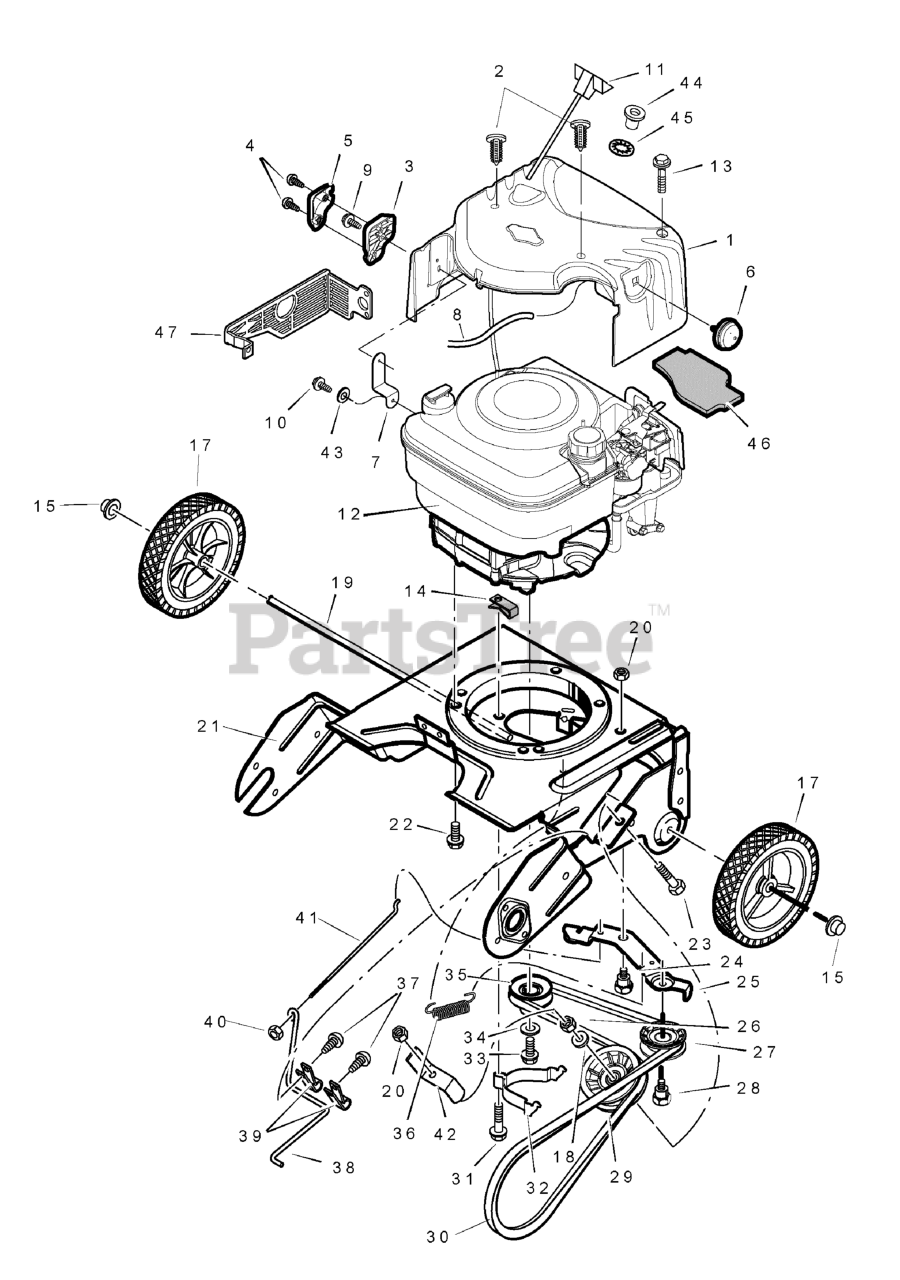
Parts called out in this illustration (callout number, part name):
1	Cover, Engine
2	Screw, #8x1.25
3	Base, Chute Rod
4	Screw, #10-14x.62
5	Cover, Chute
6	Primer-Carburetor
7	Bracket, Engine Chute
8	Hose, Primer 5 3/4 Inches
11	Grip, Standard Recoil
12	Engine
13	Bolt, #10-24x1.75
14	Retainer
15	Nut, Push Cap
17	Tire & Rim
18	WASHER, Flat, 13/32
20	Nut, 3/8-16
21	Frame, Motor Box
22	Bolt, 3/8-16x1.00
23	Screw
24	Bolt, Shoulder
25	Bracket, Idler Arm
26	Nut
27	Pulley, Idler V-Belt
28	Bolt, Shoulder
29	Pulley, Flat Idler
31	Screw, 1/4-14x1.25
32	Guide, Belt
33	Screw, 5/16-24 x 1.00
34	Washer, Sptlk .31x.58
35	Pulley, 2.50 4L .75ID
36	Spring, Extension
37	Screw, 1/4-20
38	Arm, Brake
40	Nut, 10-24
41	Rod, Adjustment
42	Guide, Belt/Brace
43	Washer, Lock
44	Guide, Rope
46	Seal, Foam
47	Guard, Muffler
